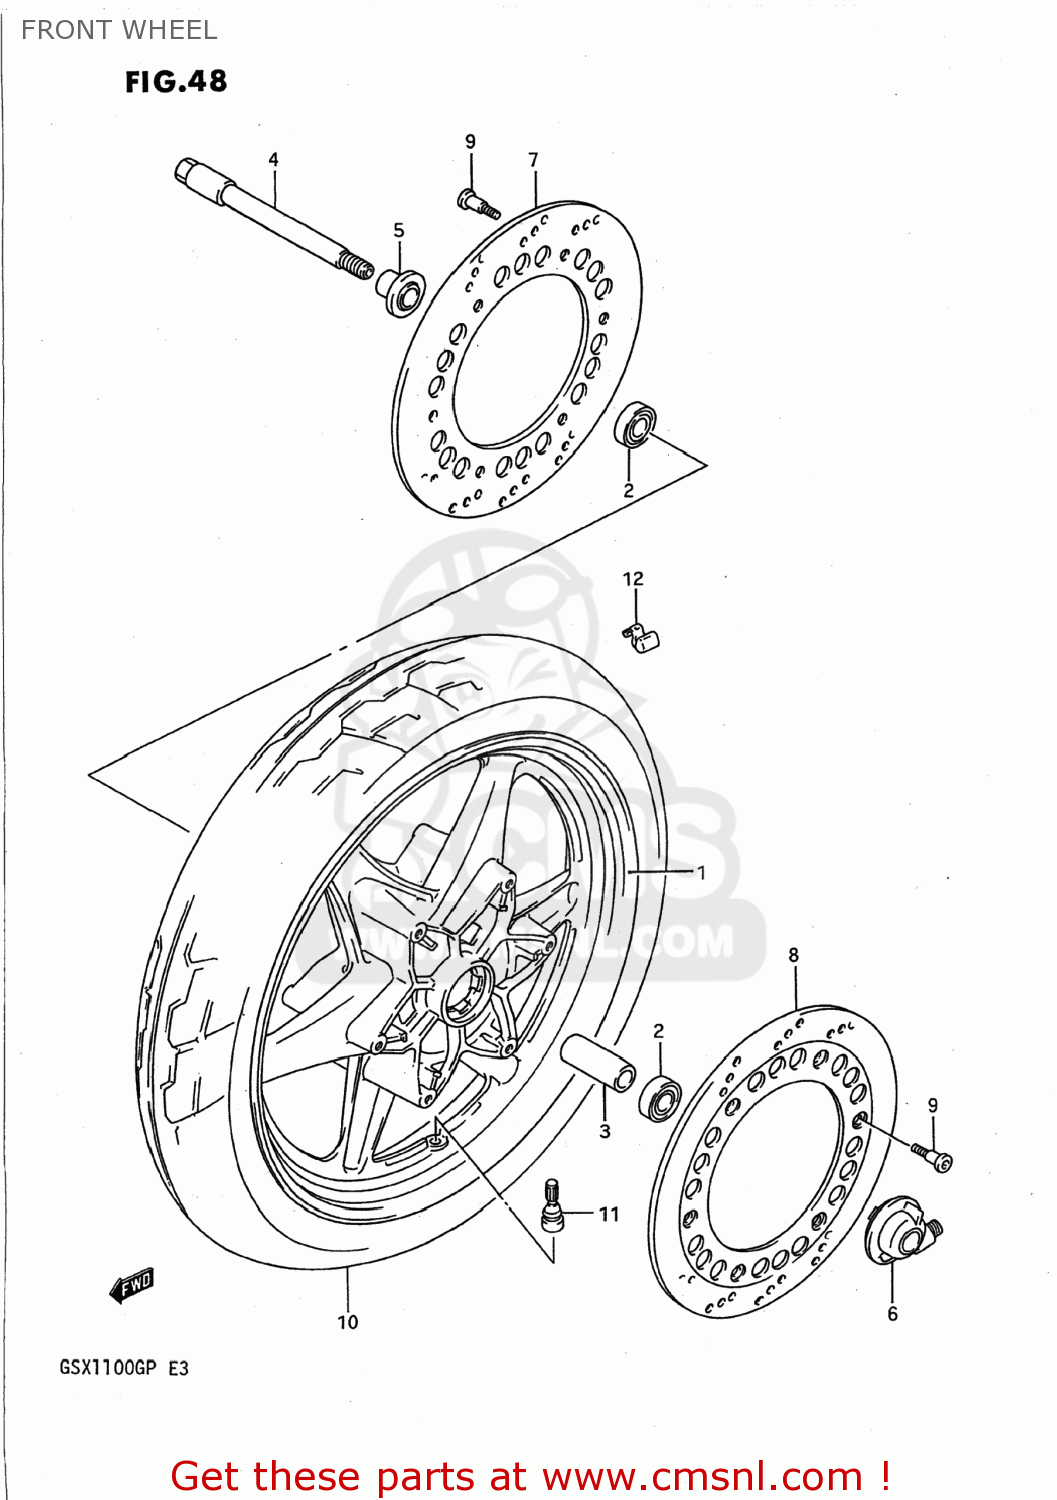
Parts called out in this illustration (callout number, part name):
1	WHEEL,FRONT
2	BEARING
3	SPACER(17.5X25X70)
4	AXLE,FR
5	SPACER COMP,FRONT AXLE
6	BOX ASSY,SPEEDOMETER GEAR
7	DISC,FR BRAKE,R
8	DISC,FR BRAKE,L
9	BOLT 8X33
10	TIRE COMP,FRONT 110/80
11	VALVE ASSY,WHEEL RIM(TR412)
12	BALANCER,WHEEL
